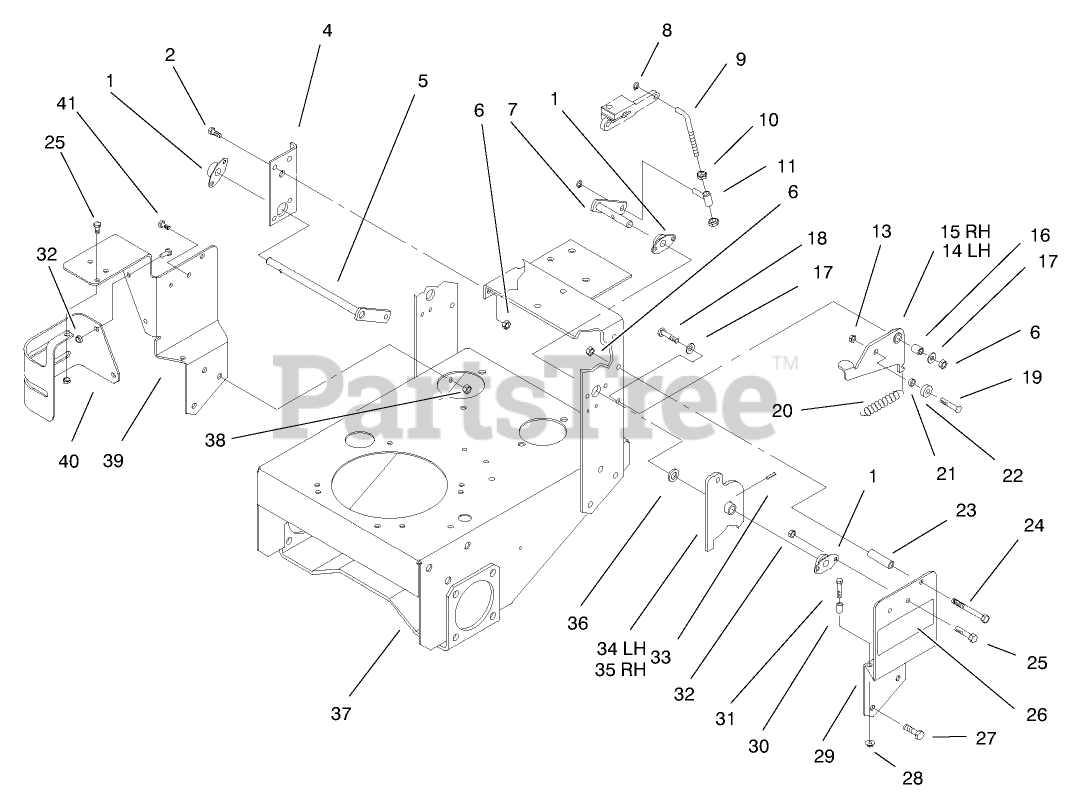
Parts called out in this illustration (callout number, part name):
1	SIDE FLANGE BEARING ASM
2	SCREW-HH
4	BRACKET-BUSHING
5	LEVER-PIVOT, RH
6	NUT-LOCK, NI
7	LEVER-PIVOT, LH
8	RING-GRIP
9	ROD-LINK
10	NUT-JAM
11	SLEEVE
13	NUT-LOCK, NI
14	ARM-DETENT, LH
15	ARM-DETENT, RH
16	BUSHING-ARM, DETENT
17	WASHER-PLAIN
18	SCREW-HH
19	SCREW-HSBH
20	SPRING-DETENT
21	SPACER-BEARING
22	BEARING-BALL
23	STOP-REVERSE
24	SCREW-HH
25	SCREW-HH
26	DECAL-HYDRO
27	SCREW-HH
28	NUT-LOCK, HHF
29	BRACKET-PIVOT, LH
30	SPACER-TUBULAR
31	SCREW-HH
32	NUT-LOCK, NI
33	PIN-ROLL, SLOTTED
34	ARM-PIVOT, LH
35	ARM-PIVOT, RH
36	WASHER-THRUST
37	FRAME WA
38	NUT-LOCK, NI
39	BRACKET-PIVOT, RH
40	GUARD-FILTER
41	SCREW-HH
